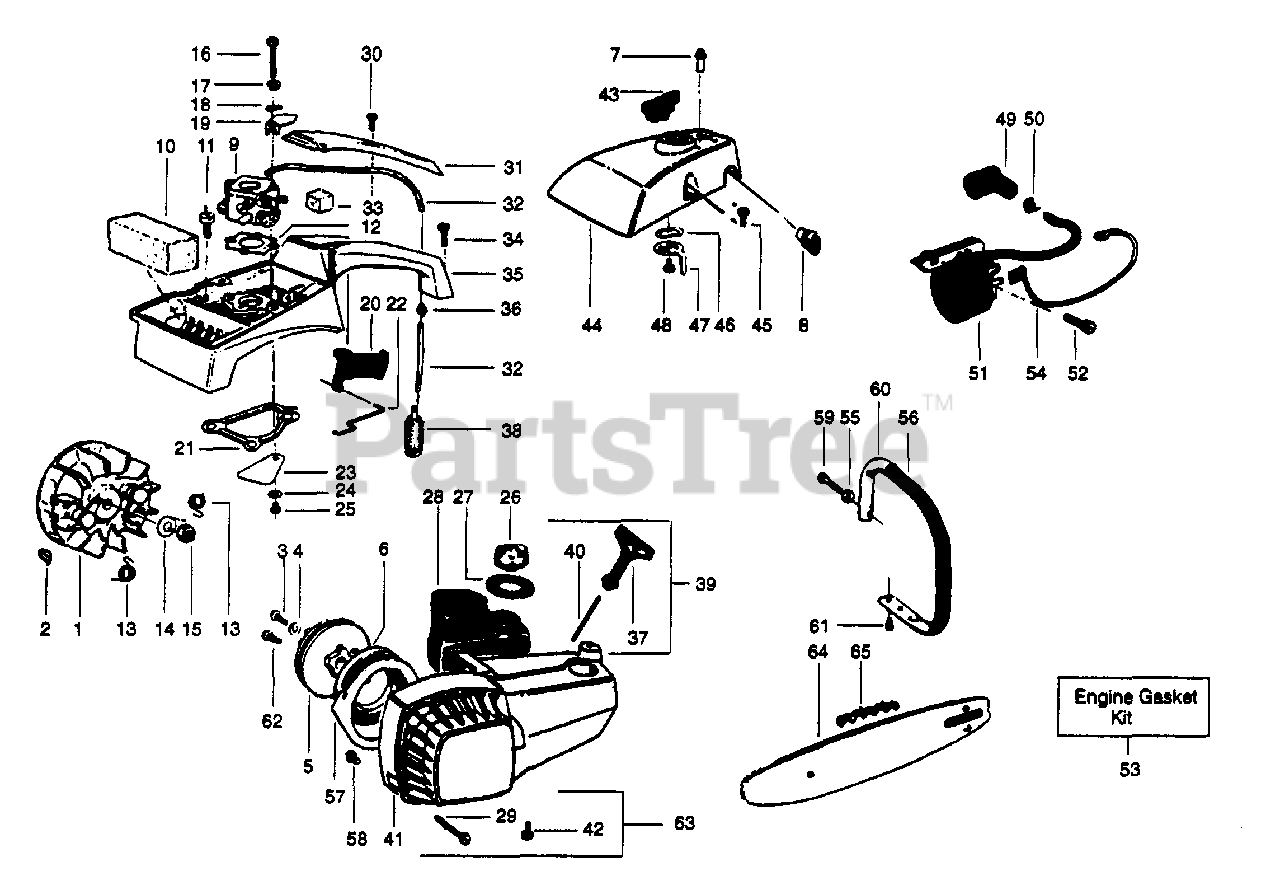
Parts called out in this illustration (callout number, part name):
1	Flywheel Ass'y.
2	Flywheel Key
3	Pulley Retaining Screw
5	Starter Pulley
6	Starter Spring
7	Grommet-Idle
8	Grommet-Mixture
9	Carburetor Kit w/Limiter Caps
10	Air Filter
12	Carburetor Gasket
13	Starter Dog Spring
14	Flywheel Washer
18	Wave Washer
19	Choke Shutter
20	Throttle Trigger
21	Gasket
22	Throttle Wire
23	Reed Valve
25	Screw
26	Fuel Cap Ass'y.
28	Fuel Tank Ass'y.
29	Screw
31	Handle Cover
33	Throttle Wire Boot
35	Handle & Carb. Hsg.
36	Fuel Line Fitting
37	Starter Handle
38	Fuel Pickup Ass'y.
39	Ass'y Rope & Handle
41	Fan Hsg. Kit
43	Choke Knob
44	Carb. Cover
46	Wave Washer
47	Choke Lever
49	Spark Plug Boot
50	Spark Plug Connector
51	Ignition Module Kit
53	Engine Gasket Kit
54	Switch Lead
56	Grip-Handlebar
57	Air Baffle
62	Rope Retaining Screw
63	Fan Hsg. Screw Kit
65	Chain
